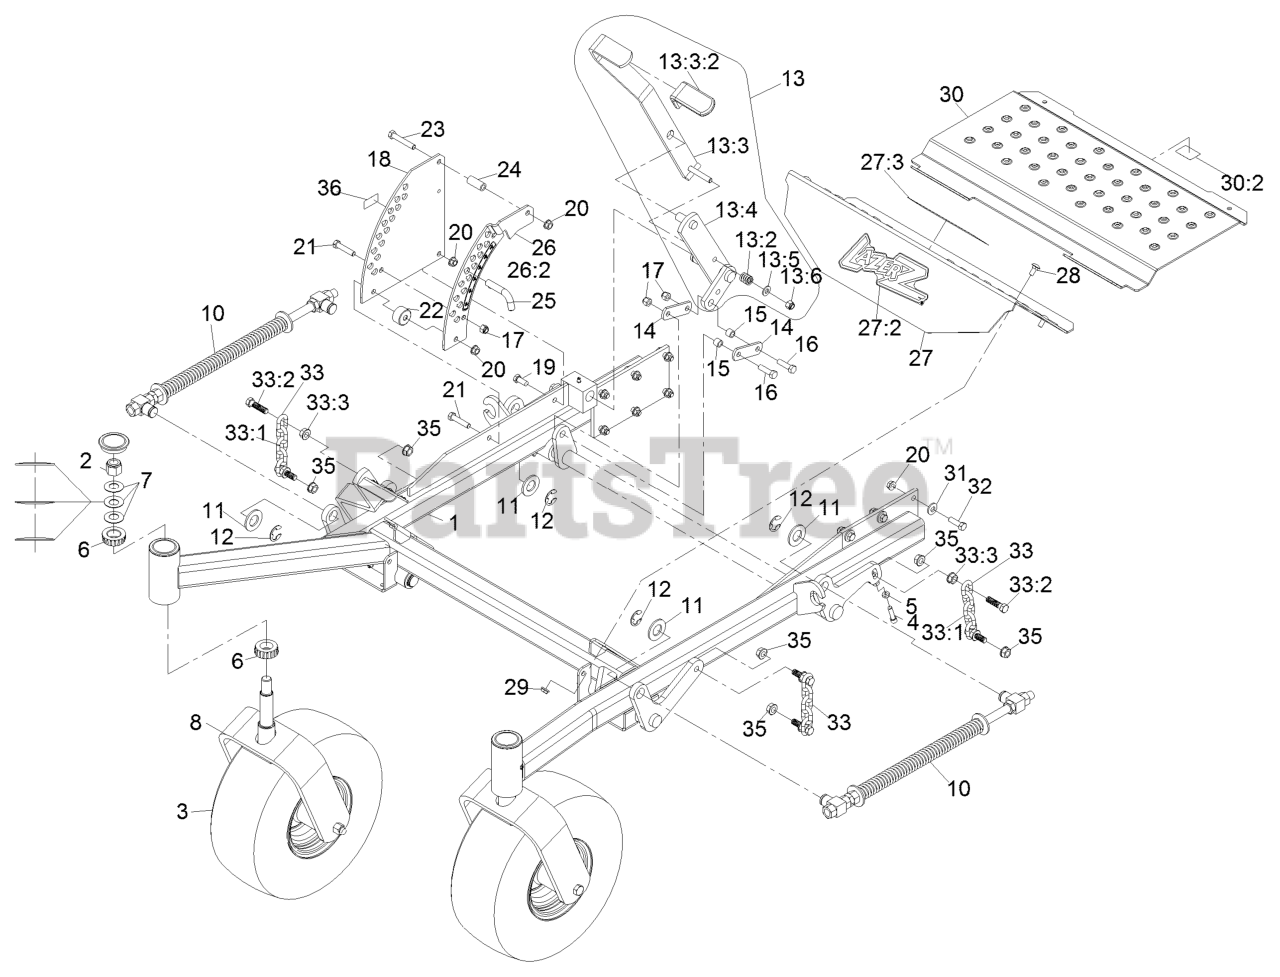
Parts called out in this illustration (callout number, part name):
1	ASM-FRT FRM 605
2	NUT-LOCK, NI
3	WHEEL & TIRE ASM
4	SCREW-HSH
5	NUT-JAM
6	Cone-Bearing Tapered Roller
7	WASHER-BELLVILLE
10	ASM,FRONT FRAME SPRING
11	WASHER-FLAT
12	RING-RETAINING, EXT
13	ASM,Deck Lift Handle
13:2	SPRING-COMPRESSION
13:3	LIFT LEVER/GRIP ASM
13:3:2	GRIP-LEVER, LIFT
13:4	WLD,ARM DECK LIFT
13:5	WASHER-FLAT
13:6	NUT-LOCK, NI
14	ARM-LIFT, DECK
15	BUSHING
16	SCREW-HH
17	NUT-LOCK, NI
18	PLATE-DECK LIFT NOTCHED O
19	SCREW-HH
20	NUT-HHF, WHIZ
21	SCREW-HH
22	Stop, Deck Height
23	SCREW-HH
24	BUSHING-LEVER, LIFT
25	PIN-HOC
26	PLATE-LIFT, DECK W/DECAL
26:2	DECAL-HEIGHT OF CUT
27	ASM, FLOORPAN FRONT W/DEC
27:2	DECAL,LAZER MODEL
27:3	DECAL-WARNING, SLOPE
28	BOLT-CARR
30	ASM, FLOORPAN LIFTOUT W/D
30:2	Decal-Guard
31	WASHER-BELLEVILLE
32	SCREW-HH
33	DECK CHAIN ASM
33:1	CHAIN-LIFT, DECK
33:2	SCREW-HH
36	Decal-Patent Ttco.Com
